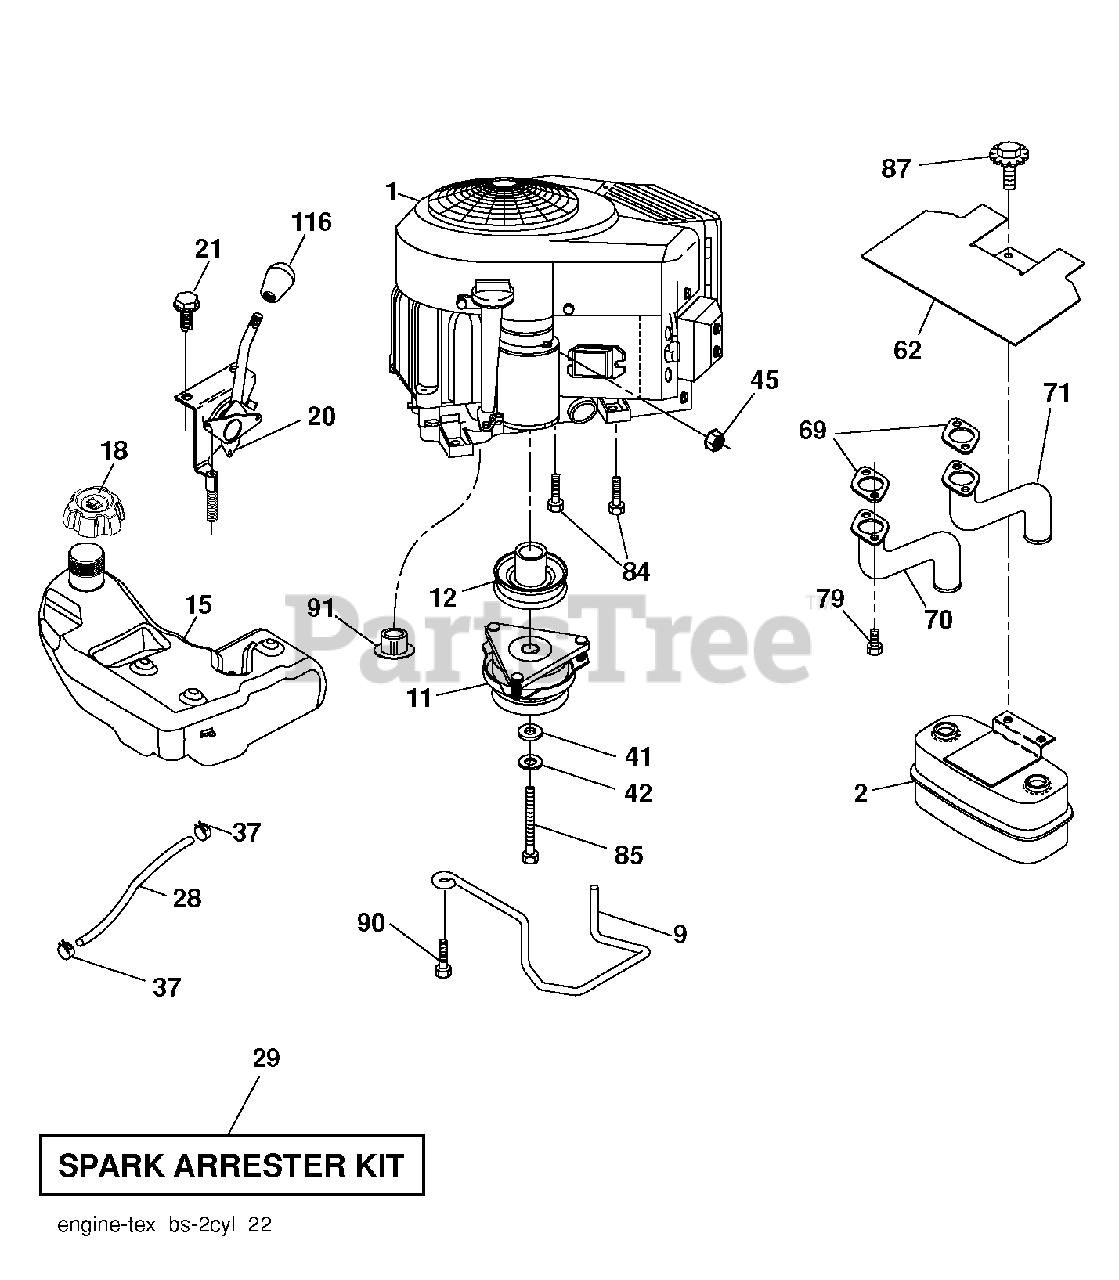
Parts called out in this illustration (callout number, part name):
1	Husqvarna TBD
2	MUFFLER.TWIN.CYL.LOW.TONE
9	KEEPER.BELT.ENGINE.4.2
11	CLUTCH.ELECTRIC.LT.48"*
12	PULLEY.ENGINE.TUFFTORQ
15	TANK.ASSY.3.GAL.EPA
18	CAP.ASM.FL.RITCH.3"E10.SYM.498
20	CONTROL THROTTLE/CHOKE
21	SCREW.#10 X 0.750.BOS
28	LINE.FUEL.64"REAR.EMIS
29	KIT.SPARK ARRESTOR 794945 B&S
37	HOSE CLAMP
42	LOCKWASHER
45	NUT
62	SHIELD.HEAT.MUFFLER
69	GASKET.MUFFLER
70	RP.EXHAUST.TUBE.LH.BS/TWIN
71	EXHAUST.TUBE.RH.BS/TWIN
79	SCREW.SOCKET.HEAD.5/16-18
84	SCREW.3/8-16
85	BOLT HEX 7/16-20X4-1/4"
87	Bolt, 5/16-18 X 1-3/4
90	SCREW 3/8-16X1
91	BUSHING.1.375OD
116	KNOB - SHIFT
